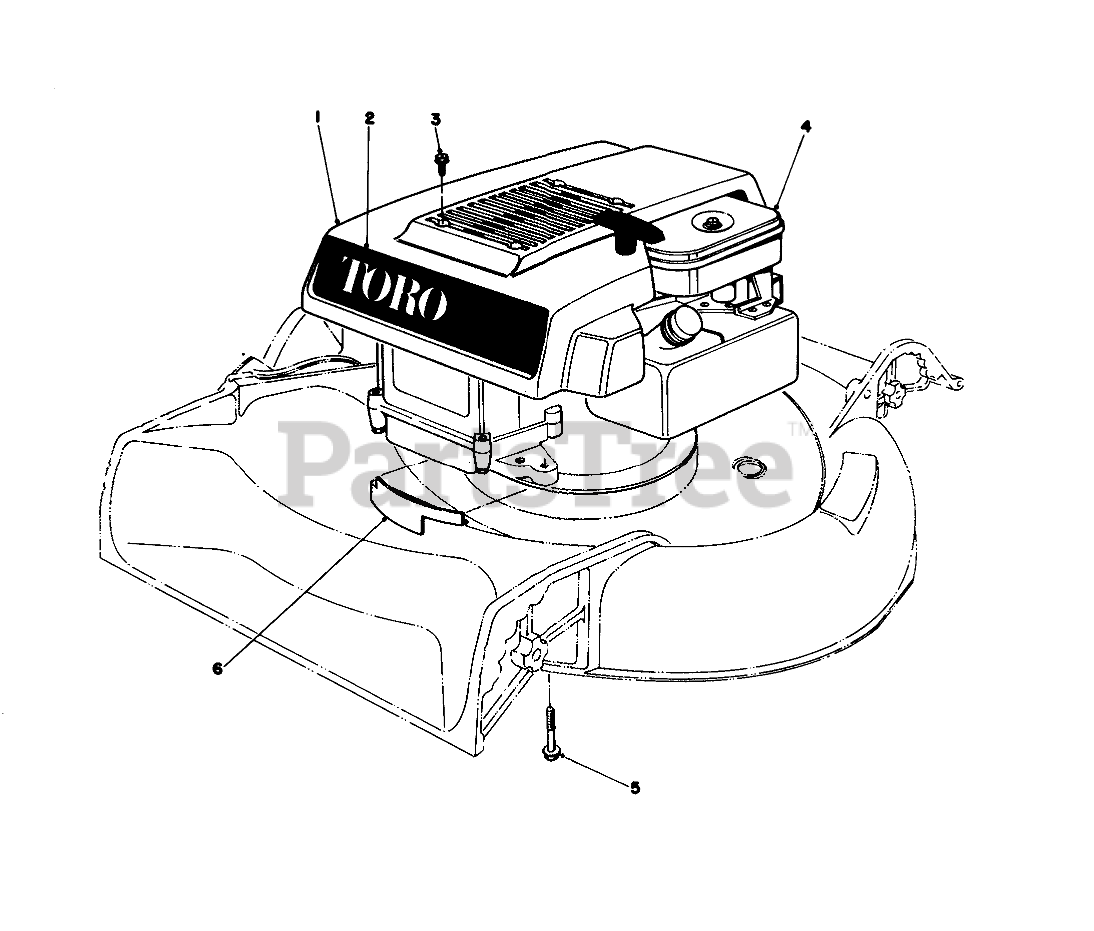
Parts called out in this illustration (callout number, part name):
1	SHROUD
2	Decal-Toro
3	8X1/2 SELF TAP SCREW
4	Engine (Model 16067)
5	3/8-16 X 2-3/4 CAPSCR
6	HOUSING CAP
